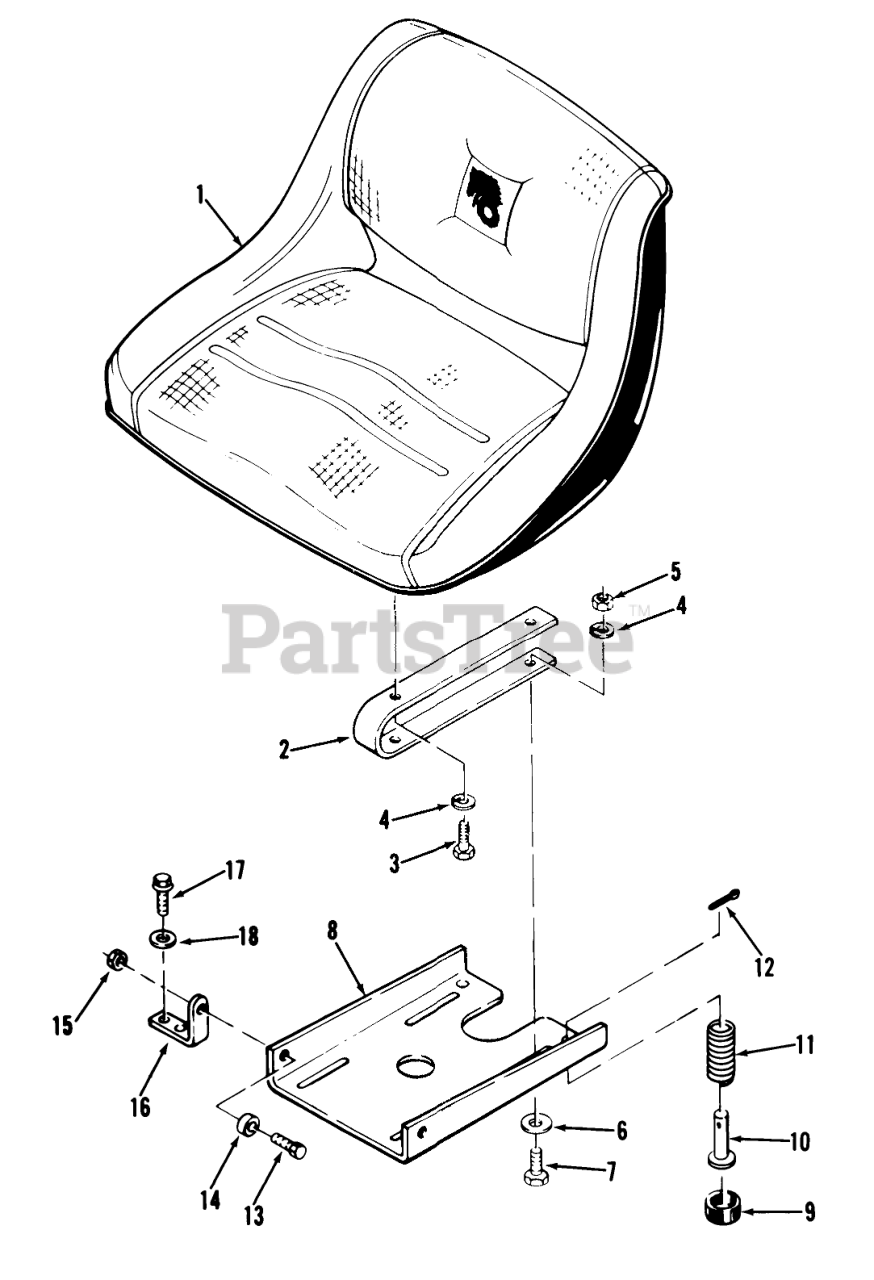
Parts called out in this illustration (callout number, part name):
1	Seat
2	Spring
3	Bolt
4	Lockwasher
5	Nut
6	WASHER 5/16 SAE
7	HHCS
8	Plate-Seat Pivot
11	SPRING
12	Cotter Pin
13	HHCS
14	BUSHING
15	Nut
16	BRACKET-PIVOT
17	Bolt
18	WASHER 5/16 SAE
